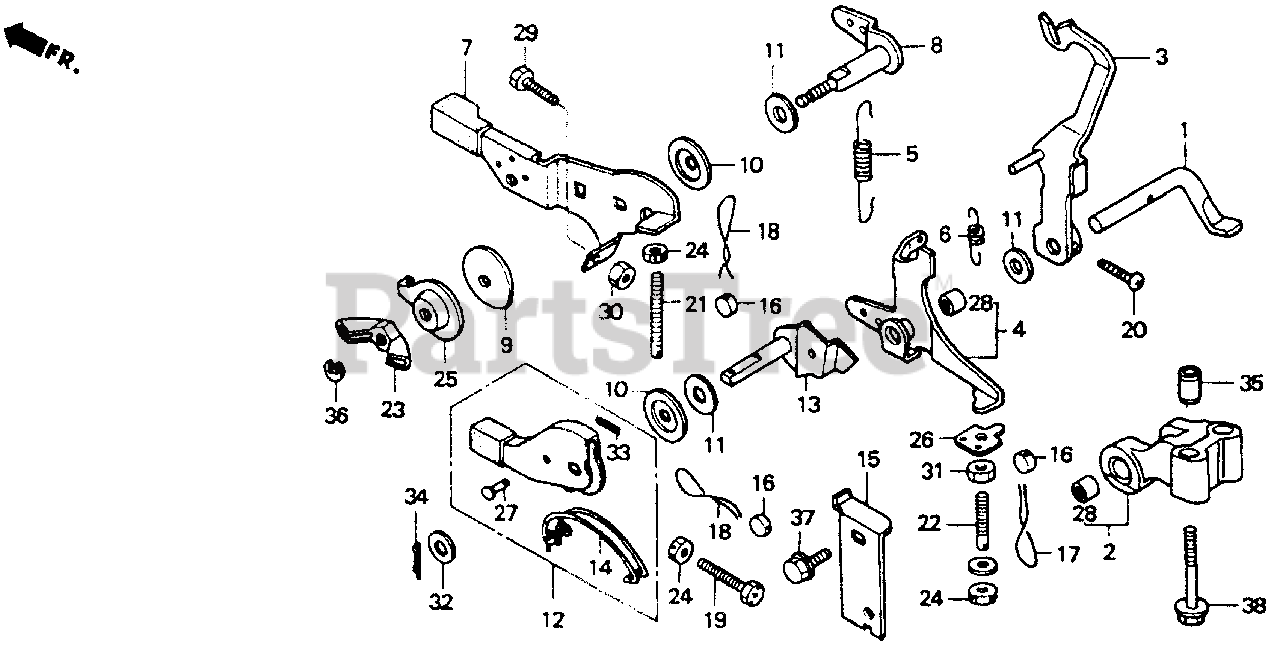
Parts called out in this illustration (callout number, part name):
1	SHAFT, GOVERNOR ARM
2	STAY, GOVERNOR SHAFT
3	ARM, GOVERNOR
4	ARM, SUB-GOVERNOR
5	SPRING, GOVERNOR
6	SPRING, IDLE
7	LEVER, CONTROL
8	SHAFT, CONTROL LEVER
9	SPRING, LEVER
10	SPACER, CONTROL LEVER (A)
11	SPACER, CONTROL LEVER (B)
12	LEVER, STOP
13	SHAFT, STOP LEVER
14	SPRING, STOP LEVER
15	HOLDER, STOP CABLE
16	END, LOCK
17	WIRE, LOCK (A)
18	WIRE, LOCK (B)
19	BOLT, RECESSED (6X32)
20	SCREW, PAN (3X18)
21	BOLT, CONTROL ADJUSTING
22	BOLT, ADJUSTING
23	NUT, PLUG COVER
24	NUT, HEX. (6MM)
25	WASHER (6X30)
26	WASHER, SEALING
27	PIN, CENTER (4X16.5)
28	BEARING, NEEDLE (8X12X10) (TOYO)
29	BOLT, SLOT (6X20)
30	NUT, HEX. (6MM)
31	NUT, HEX. (6MM)
32	WASHER, PLAIN (8MM)
33	PIN, COTTER (1.6)
34	PIN, COTTER (2.5MM)
35	PIN A, DOWEL (8X14)
36	E-RING (3MM)
37	BOLT, FLANGE (6X16)
38	BOLT, FLANGE (6X40)
